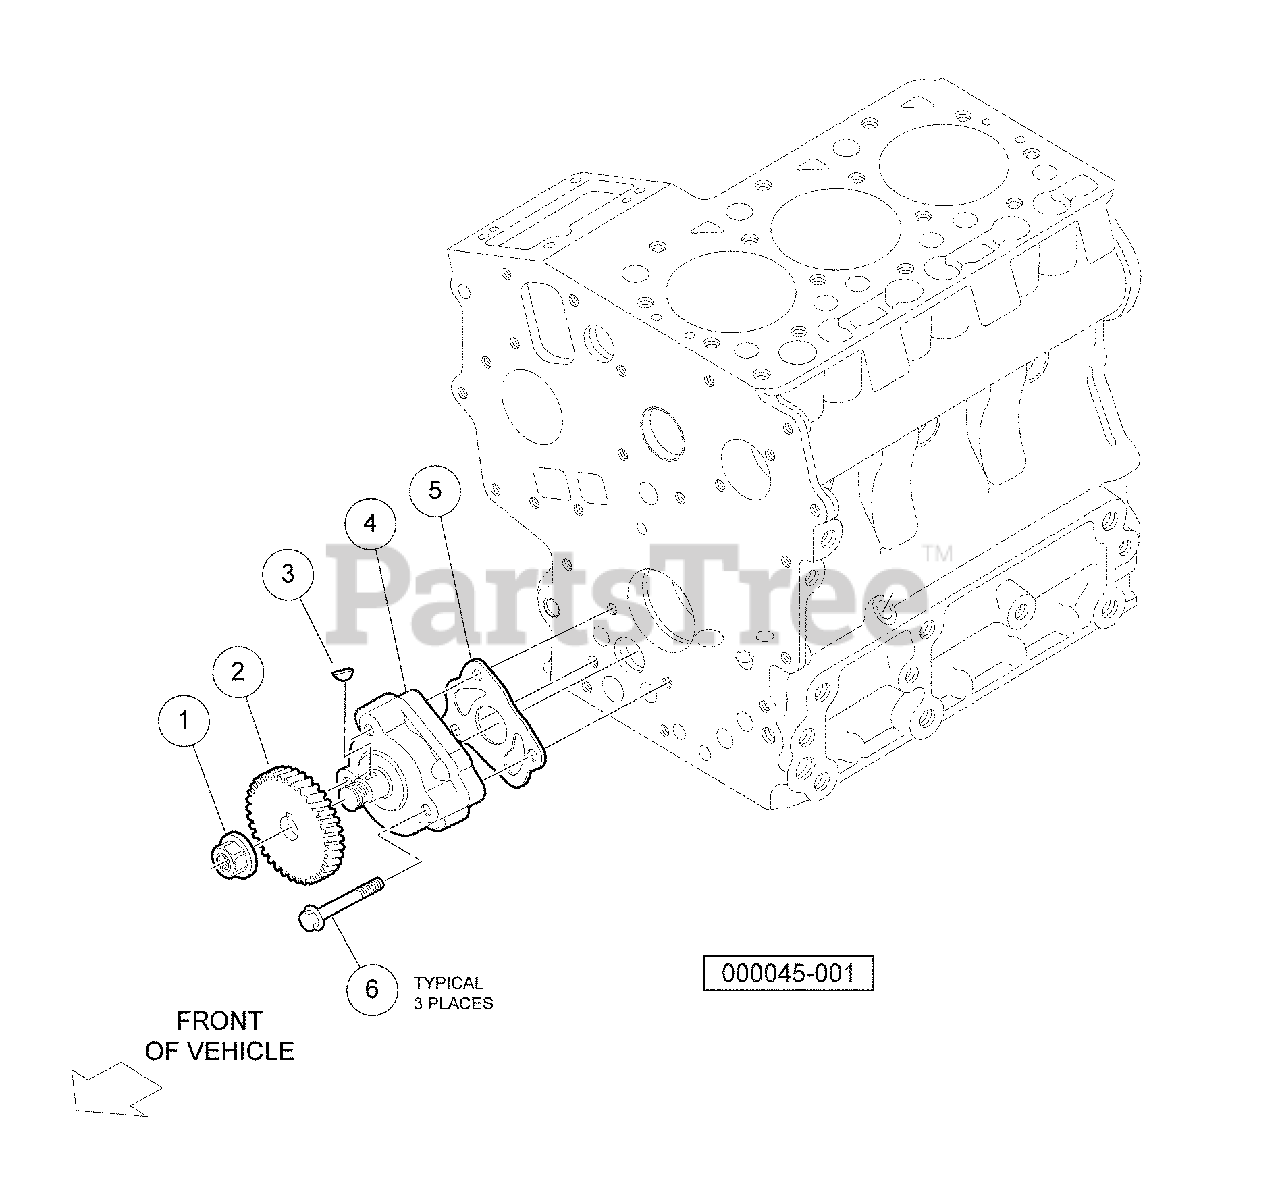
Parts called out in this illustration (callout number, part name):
1	Nut, Flange, D722 Oil Pump
2	Gear, Oil Pump Drive
3	Key, Feather, 8x4
4	Assy, Pump, Oil
5	Gasket, Oil Pump
6	Bolt, Oil Pump
